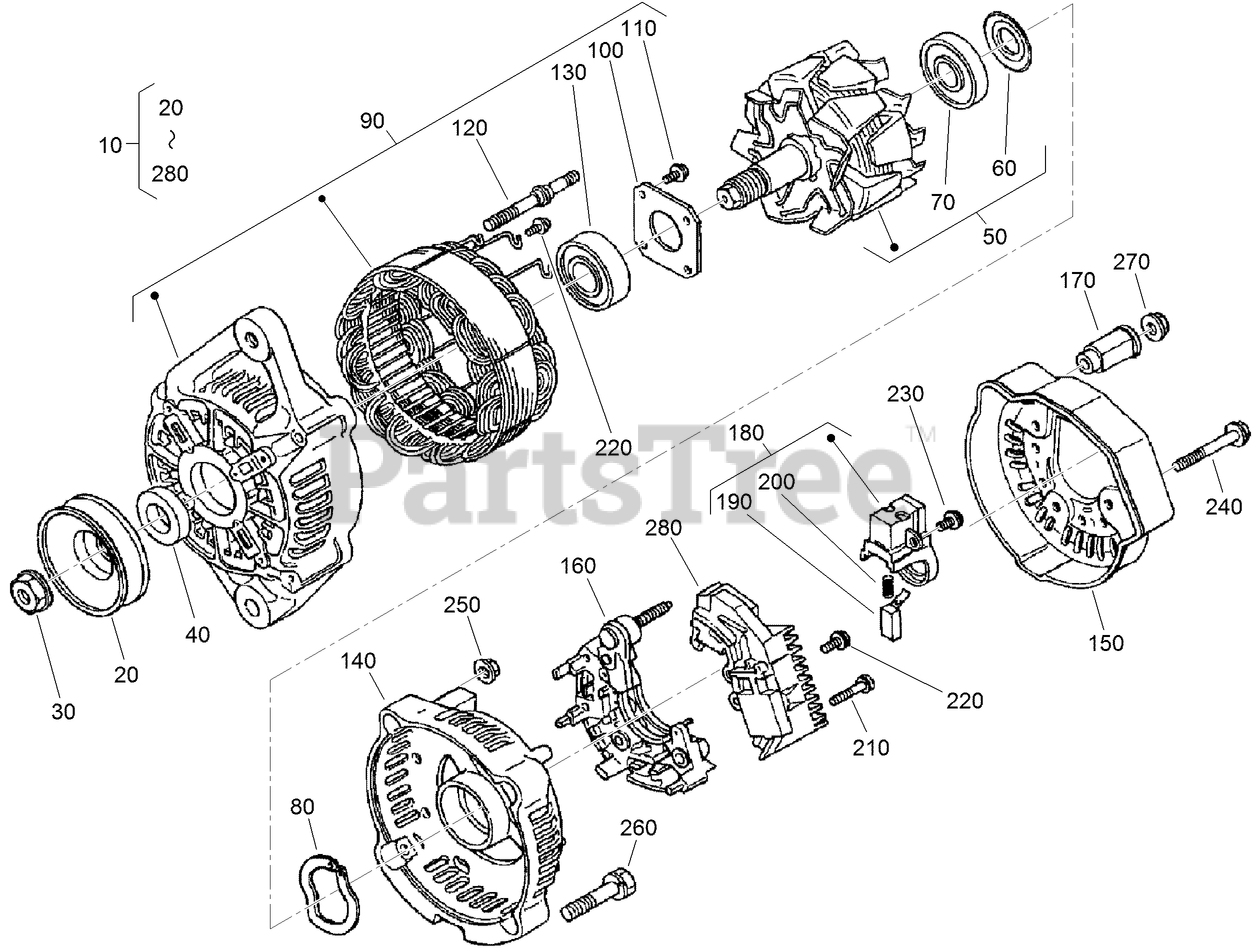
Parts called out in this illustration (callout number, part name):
10	ALTERNATOR ASM
20	PULLEY-DYNAMO
40	COLLAR
50	Rotor ASM
60	COVER-BEARING
70	Bearing-Ball
80	WASHER-THRUST
90	Drive End Frame ASM
100	PLATE-RETAINER
110	SCREW-HEAD, ROUND
120	BOLT-THROUGH
130	Bearing-Ball
140	FRAME-END
150	Cover-End
160	RECTIFIER ASM
170	BUSHING-INSULATION
180	Brush Holder ASM
190	BRUSH
200	SPRING-BRUSH
210	SCREW-HEAD, ROUND
220	SCREW-HEAD, ROUND
230	SCREW-HEAD, ROUND
280	REGULATOR ASM
